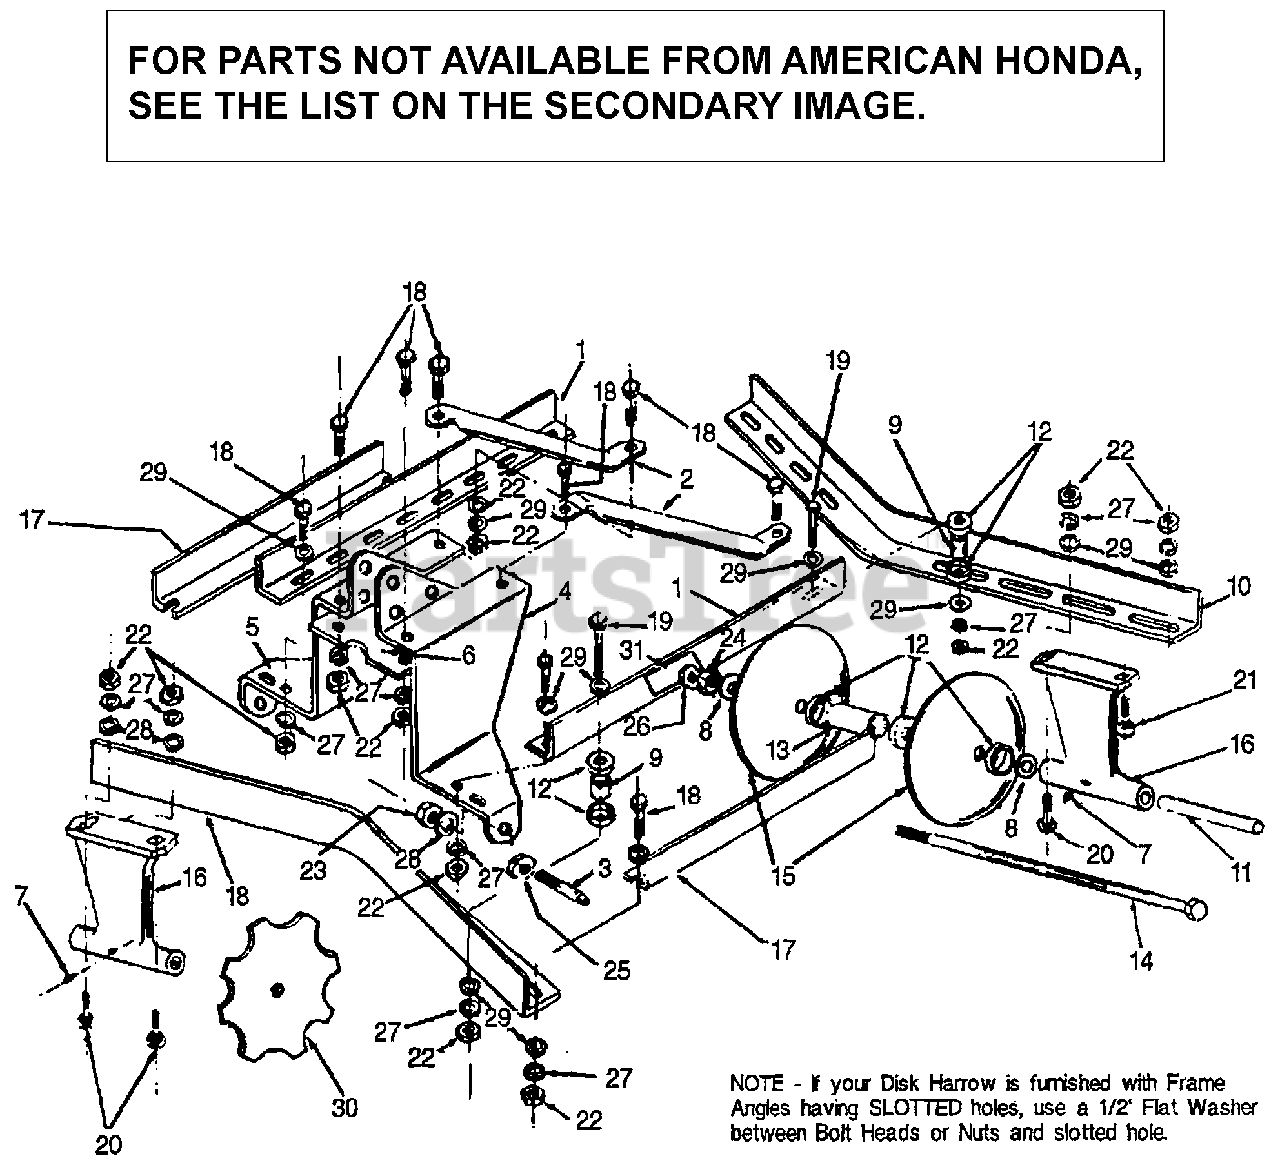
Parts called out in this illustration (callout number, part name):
7	FITTING, GREASE
9	SPACER, FRAME
11	TUBE, BEARING
12	WASHER, CENTERING
13	SPACER, DISK (NOT AVAILABLE)
14	BOLT, HEAD HEX. (3/4X20")
15	BLADE, DISK PLAIN (12")
16	HANGER, DISK (NOT AVAILABLE)
30	BLADE, DISK NOTCHED (12")
